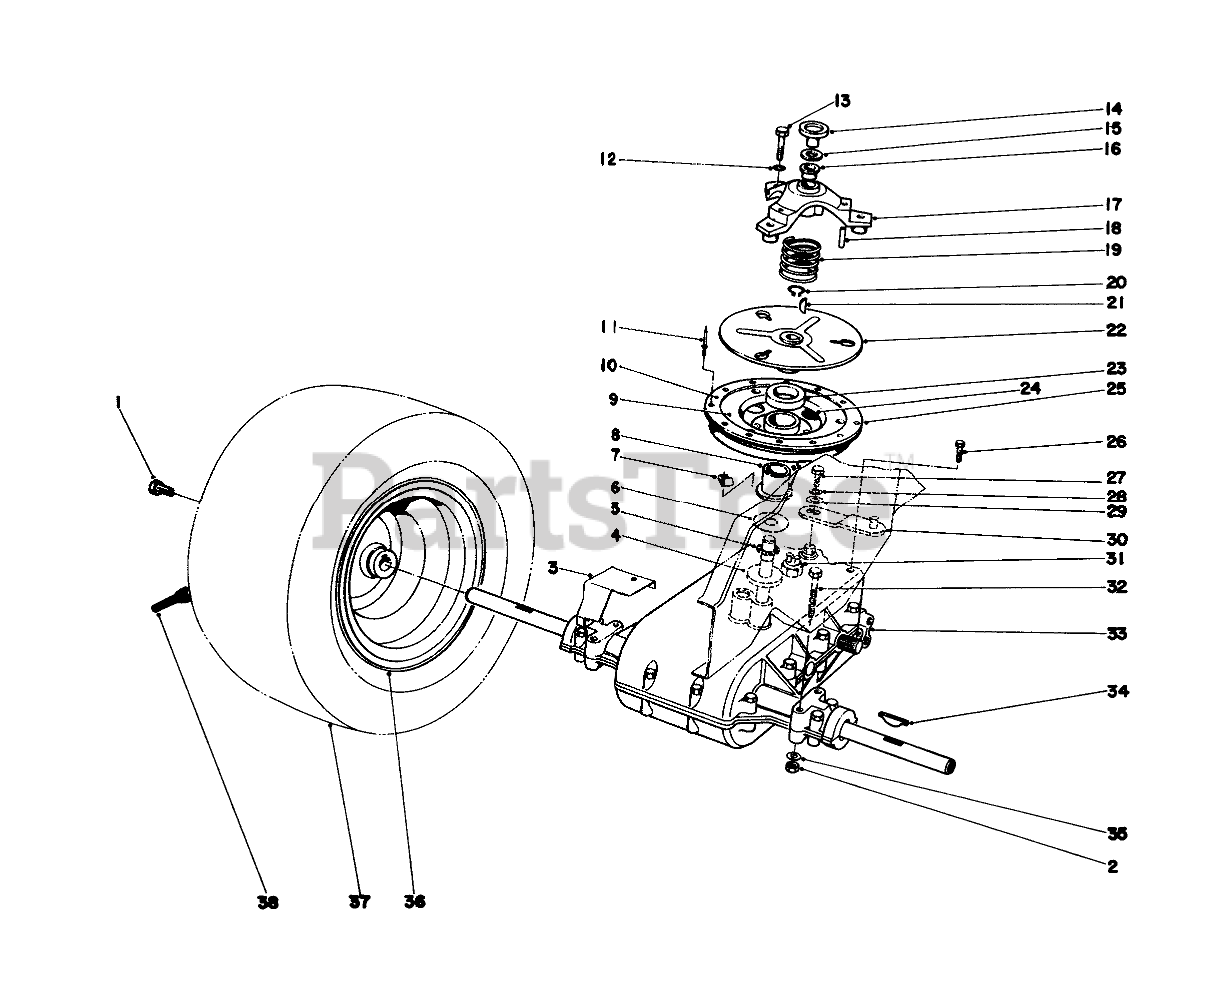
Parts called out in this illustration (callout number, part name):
1	CAPSCREW 3/8 16 3/4
2	NUT-LOCK, CONE
3	GRASS SHIELD B
4	SPACER
5	NEEDLE BRG
6	THRUST WASHER
7	CLIP-FUEL LINE
8	Bushing
9	Retainer Ring
10	CLUTCH PAD
11	Rivet
12	WASHER-LOCK
13	SCREW-HH
14	CLUTCH CAP
15	THRUST RACE
16	BUSHING-FLANGE
17	Cover Assembly (Incl. Ref. #16 & 18)
18	NEEDLE BRG
19	COMPRESSION SPRING
20	RING-SNAP, EXTERNAL
21	KEY-WOODRUFF
22	Clutch Plate
23	WASHER FELT
25	Sheave Assy. (Incl. Ref. #8-11)
26	SCREW-HWHTF
27	SCREW-HH
28	WASHER-LOCK
29	WASHER-FLAT
30	SHIFT LEVER WA B
31	NEUTRAL SWITCH
32	SCREW-HH
33	Transaxle
35	WASHER-PLAIN
36	REAR RIM
37	Tire
38	STEM-VALVE
